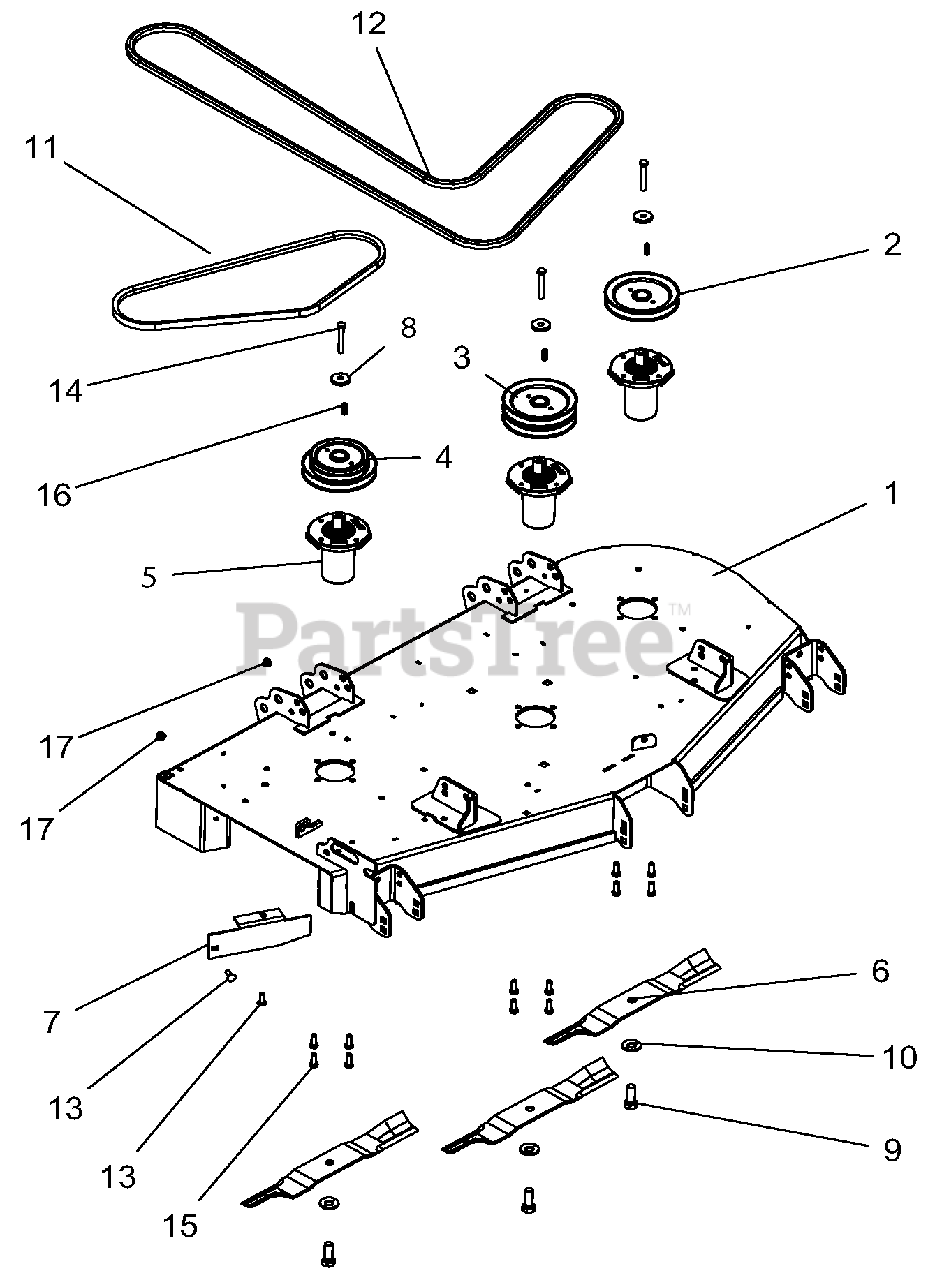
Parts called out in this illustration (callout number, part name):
1	KIT, 52" MOWER DECK W/SAFETY DECALS-RED
2	PULLEY, SINGLE -1" ID X 6.00" OD-BLACK
3	PULLEY, DOUBLE -1" ID X 6.00" OD-BLACK
4	PULLEY, DOUBLE -1" ID X 6.00" & 4.75" OD
5	SERVICE, ASM SPINDLE- DUCTILE
6	BLADE, 18"
7	BAFFLE, DISCHARGE, 52"-RED
8	RETAINER, SHEAVE SPINDLE
9	BLT, HEX .62-18X1.75 GR8 YWZC
10	WSHR, BLVL .63X1.625X.14
11	BELT, B 56.00 RAW COGGED
12	BELT, BB 118.00 WRAPPED HEX
13	BLT-RDHDSQSHNK .31-18X1.00 G5 Y
14	BLT-HEX .38-16X2.75 GR8 YWZC
15	BLT-HEX .38-16X1.00 GR5 YWZC EP30
16	KEY-SQ .250X.250X1.00 RC 40-50
17	NUT-LK-NYL-FLG .31-18 YWZC
